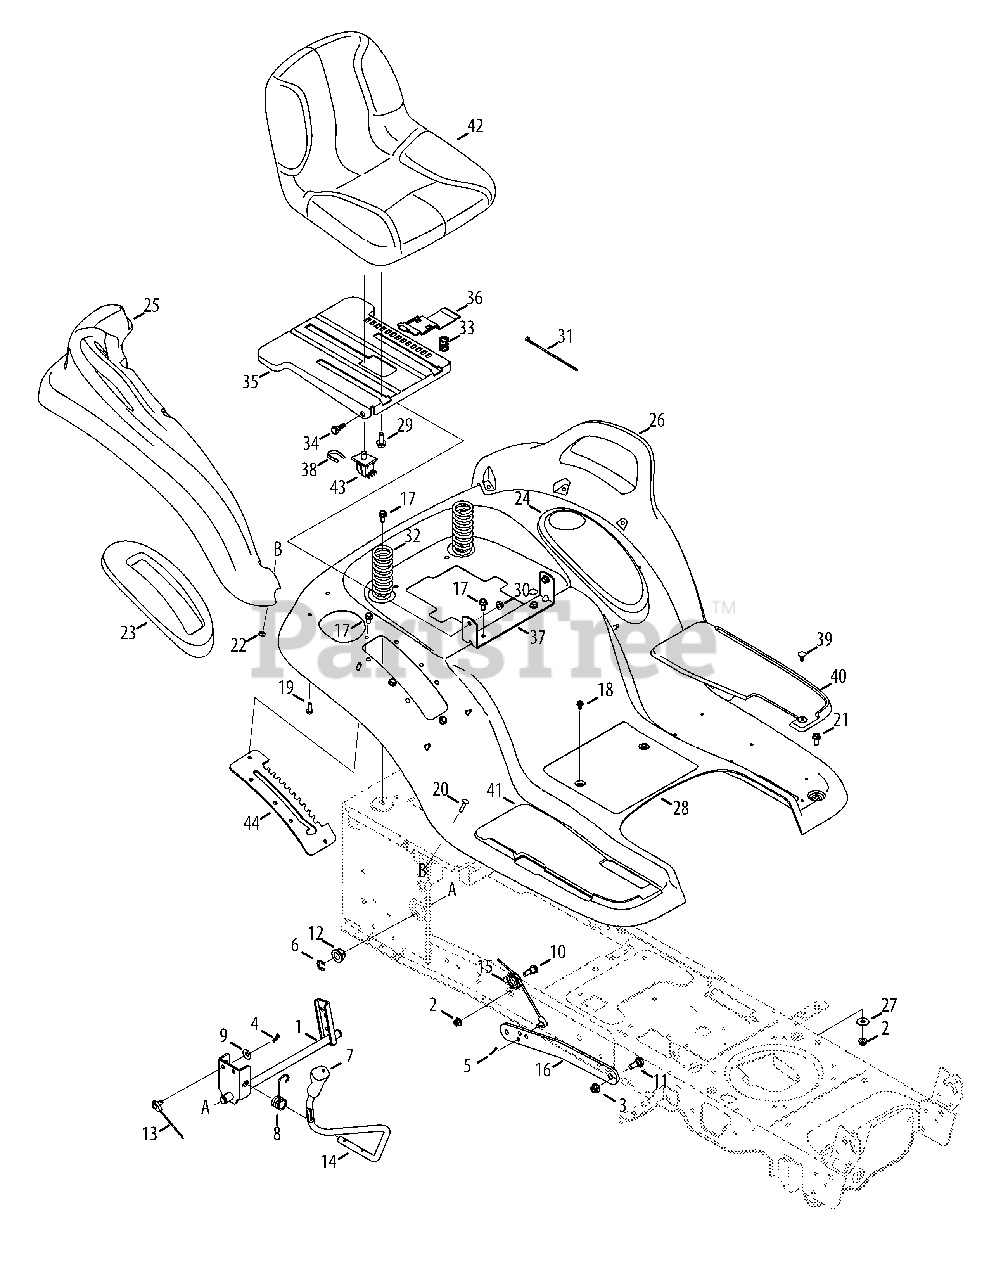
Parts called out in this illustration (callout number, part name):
1	Lift Shaft Assembly
2	Flangelock Nut, 5/16-18
3	Flangelock Nut, 3/8-16
4	Cotter Pin, .072 DIA. x 1.13 LG
5	Bow-Tie Cotter Pin
6	E-Ring, .625 DIA. SHAFT
7	Handle Grip
8	Torsion Spring
9	Spring Washer, .401 x .870 x .063
10	Shoulder Screw, .437 x .470 x 5/16-18
11	Shoulder Bolt, .500 x .270 x 3/8-16
12	Hex Flange Bearing
13	Lift Cable, 16.16 LG
14	Lift Handle
15	Pulley Roller Cable
17	Taptite Screw, Lock Washer, 5/16-18 x .750
18	Taptite Screw, Lock Washer, 1/4-20
19	Hi-Lo Screw, Lock Washer, 1/4-15
20	Carriage Screw, 1/4-20 x 1.00
21	Taptite Screw, 5/16-18 x .750
22	Sems Nut, 1/4-20
23	Lift Lever Cover
24	Cover with Cup Holder
25	RH Fender Flare
26	LH Fender Flare
27	Flat Washer, .344 x 1.00 x .063 HDN
29	Hex Head Flange Bolt, 3/8-16 x .875
30	Flangelock Nut, 5/16-18
31	Cable Tie, 3/16 x .05 x 7.4
32	Compression Spring, 1.50 x 3.90 x .200
33	Compression Spring, .68 x 1.065 x .055
34	Shoulder Screw, .437 x .268 x 5/16-18
35	Seat Mounting Bracket
36	Seat Adjustment Lever
37	Seat Pivot Bracket
38	Switch Retainer Clip
39	Ratchet Clip
40	LH Foot Pad
41	RH Foot Pad
42	Seat
43	Seat Switch
